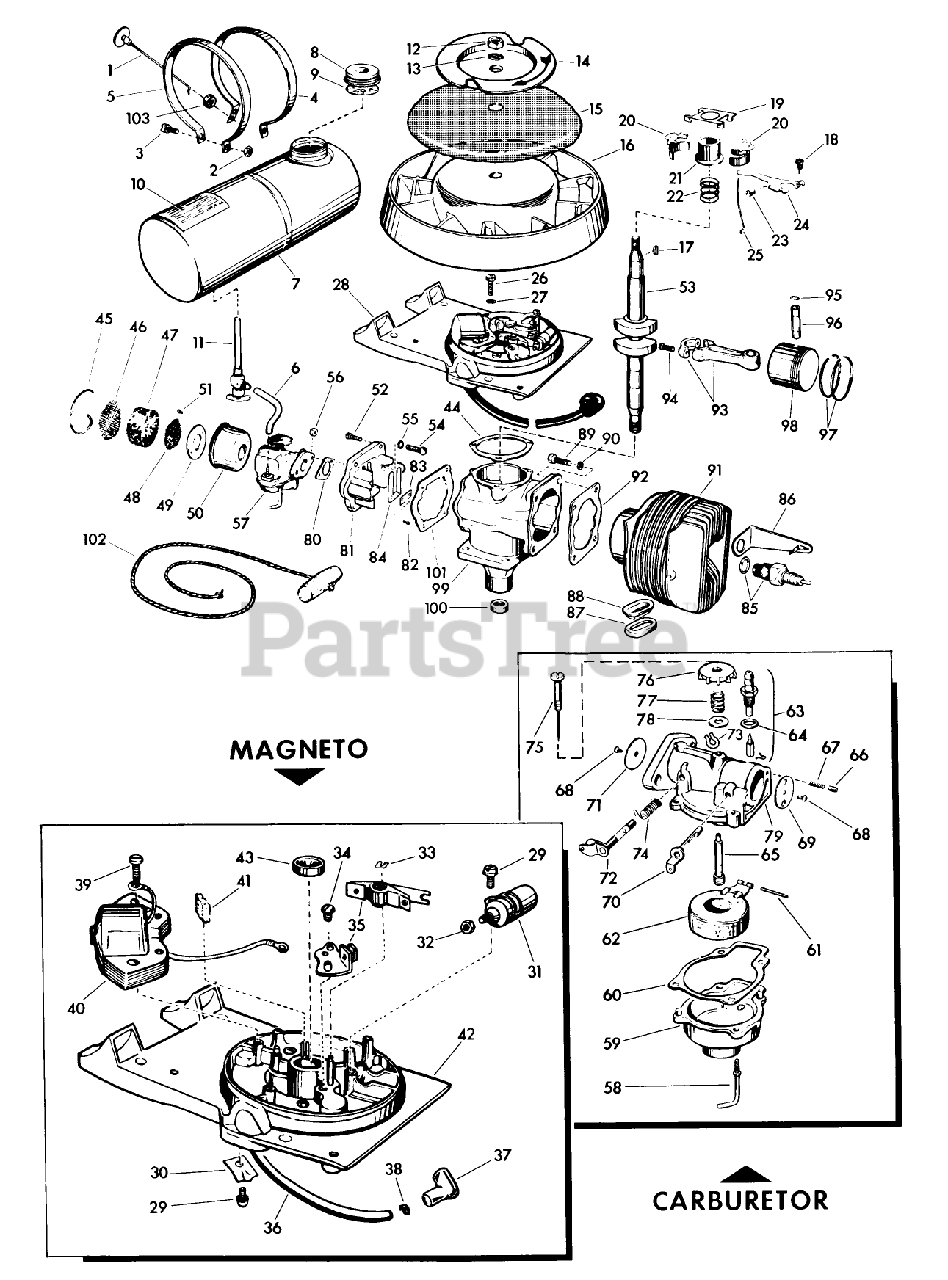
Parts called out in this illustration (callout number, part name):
2	Nut-Tank Strap Screw
3	Screw-Tank Strap
4	Strap-Gas Tank, Left
5	Strap-Gas Tank, Right
8	Gas Cap
11	VALVE&SCREEN SM
14	Pulley-Starter
15	Screen-Flywheel
21	COLLAR S
23	WEAR BLOCK S
24	GOVERNER LEVER AY
25	GOVERNOR ROD S
26	Screw-Pulley to Cap
27	Washer-Lock, Pulley
33	Spring Clip-Breaker Post
35	BREAKER AY. S
37	Cover-Rubber
41	Oiler Wick
44	GASKET S
47	ELEMENT
49	BACK-UP PLATE
52	SCREW S
53	Crankshaft
56	STOP NUT
68	Screw-Choke Disc
74	SPRING
75	NEEDLE AY. S
77	Spring-Ndl. Adj.
78	Washer-Needle Adjustment
80	GASKET S
83	PLATE-BACKUP, REED
85	Spark Plug
90	Washer-Lock, Cylinder to Crankcase
91	Cylinder Sleeve Assembly
94	Screw-Connecting Rod
97	Ring-Piston
103	Block-Friction, Knob
